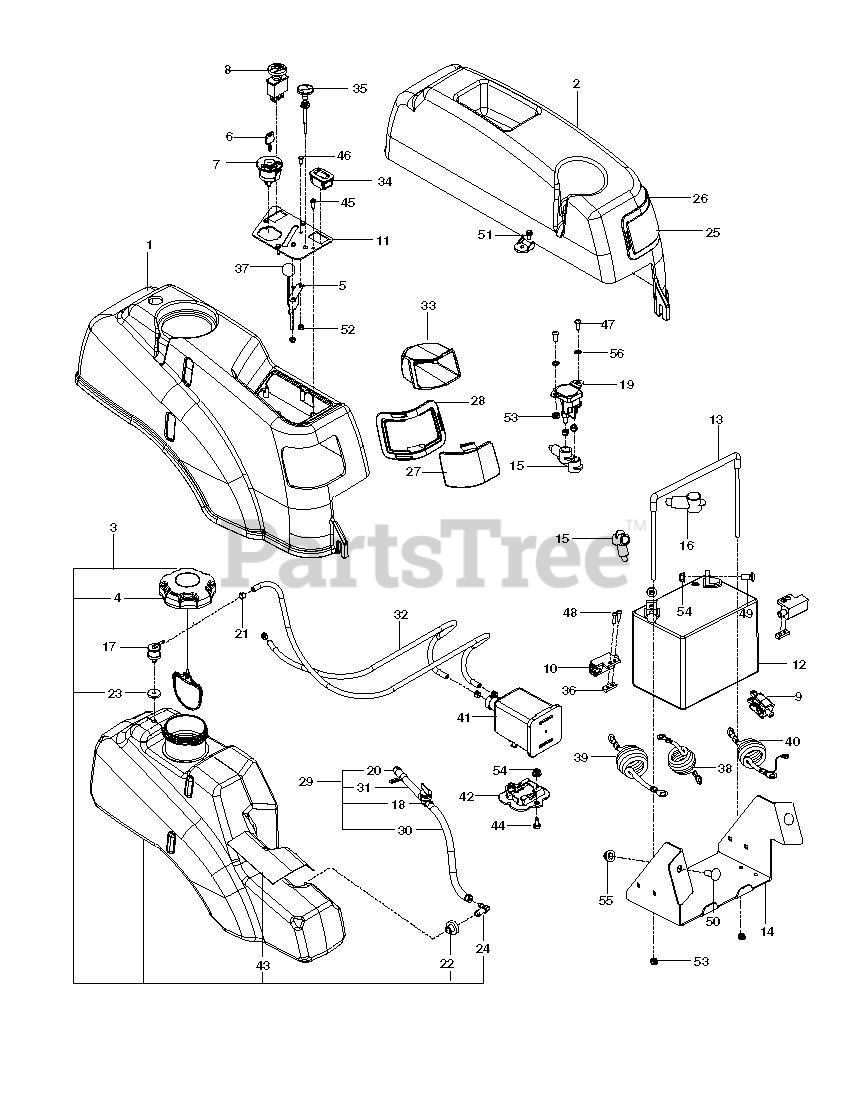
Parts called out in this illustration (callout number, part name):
1	FENDER RT, BLACK
2	FENDER, LT, BLK
3	FUEL TANK ASM, LARGE
4	CAP, FUEL
5	THROTTLE CABLE
7	IGNITION SWITCH
9	SWITCH, BRAKE 3P
13	BATTERY TIE DOWN ASSEMBLY
14	BOX, BATTERY, BLACK
15	TERMINAL COVER-SM
16	INSULATOR
17	VALVE.FUEL.CHECK
18	FUEL VALVE
19	SOLENOID
20	HOSE CLAMP
21	CLAMP, HOSE
22	RUBBER GROMMET
23	GROMMET, CHECK VALVE
25	RING, LT BLK
27	RING, TRIM, RT-BLK
29	FUEL LINE ASSY
30	GAS LINE 10"
31	FUEL LINE 2.5"
32	FUEL LINE 33"
35	CHOKE CABLE
36	TAPPED PLATE
37	KNOB ROUND BALL
38	CABLE POSITIVE, LONG
39	BATTERY CABLE, NEGATIVE
41	CANNISTER, CARBON
42	BRACKET, CANISTER
45	SCR #10-12X3/4 HEX WAS HD ZD
46	HCS #10-24 X 1/2
47	SCR 1/4-20 X 5/8 BTN SKT HD ZD
48	SCR #10-24 X .75 SKT HD BLK
49	BOLT 5/16C X 3/4" CARRIAGE
50	RHSNB 3/8C X 1
51	BOLT 1/4-20 X 1/2 HWST
52	NUT 10-24 NYLOC
53	NUT 1/4-20 NYLOC
54	5/16-18 NYLOC FLANGE NUT
55	NUT 3/8-16 HEX FLG NYLOC ZD
56	WASHER 1/4 INT TOOTH
